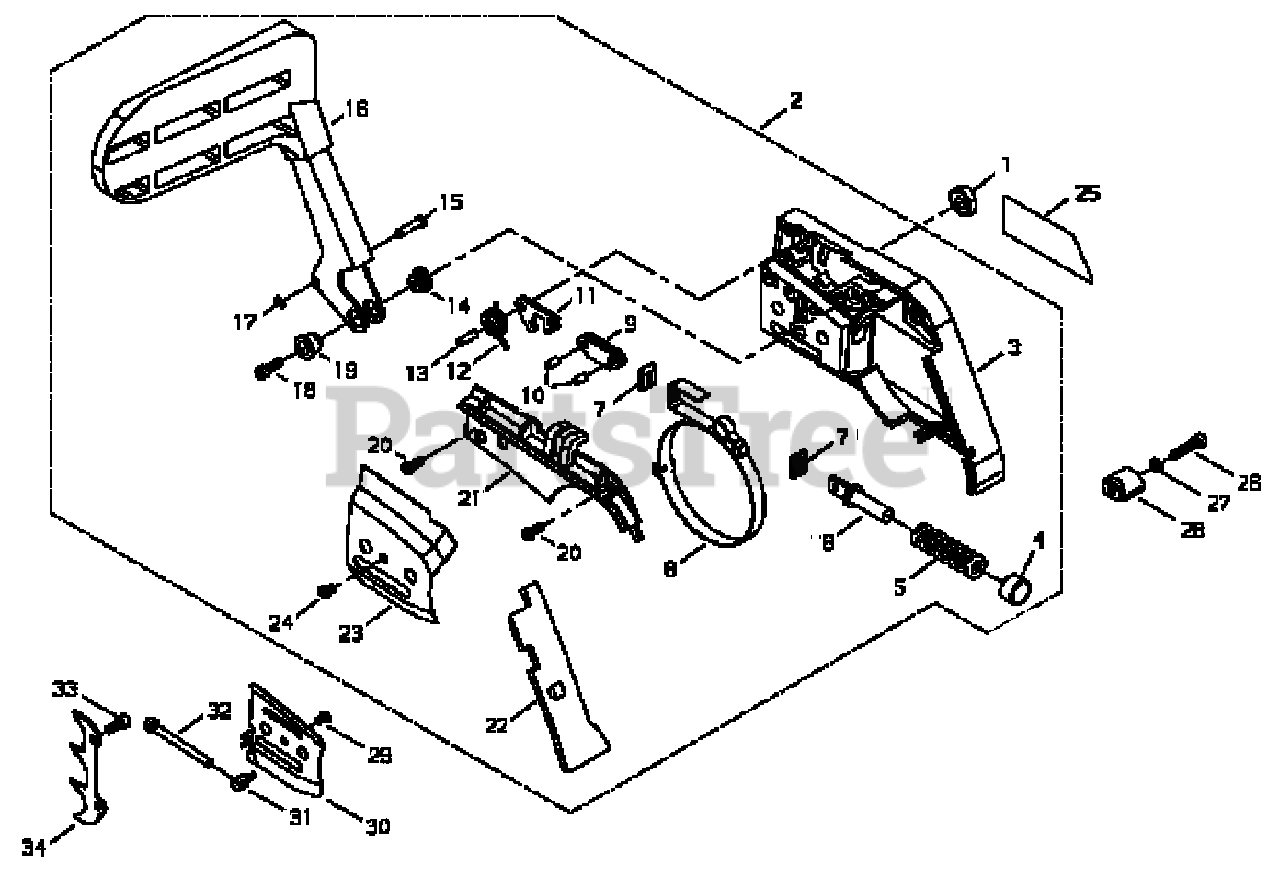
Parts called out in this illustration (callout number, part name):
1	NUT 8
2	BRAKE ASSY
3	GUARD, SPROCKET
4	STOPPER
5	SPRING, BRAKE
6	HOLDER, SPRING
7	PLATE, ADJUST
8	BAND, BRAKE
9	STRAP, TIE
10	PIN, LOCATING Ø4×8
11	LEVER, INNER
12	SPRING, LEVER
13	PIN, LOCATING
14	NUT
15	PIN, LEVER
16	LEVER, BRAKE
17	RING, SNAP 3 MM
18	BOLT 4×12
19	HOLDER
20	SCREW, TAPPING 4×12
21	COVER
22	PROTECTOR
23	PLATE, GUIDE - INNER
24	SCREW, TAPPING 4×8
25	LABEL, TRADE
26	BOLT M5×25
27	WASHER 5 MM
28	CHAIN CATCHER
29	SCREW M4×7
30	PLATE, GUIDE
31	TENSIONER, CHAIN
32	SCREW, SLIDE
33	BOLT
34	SPIKE, BUMPER
